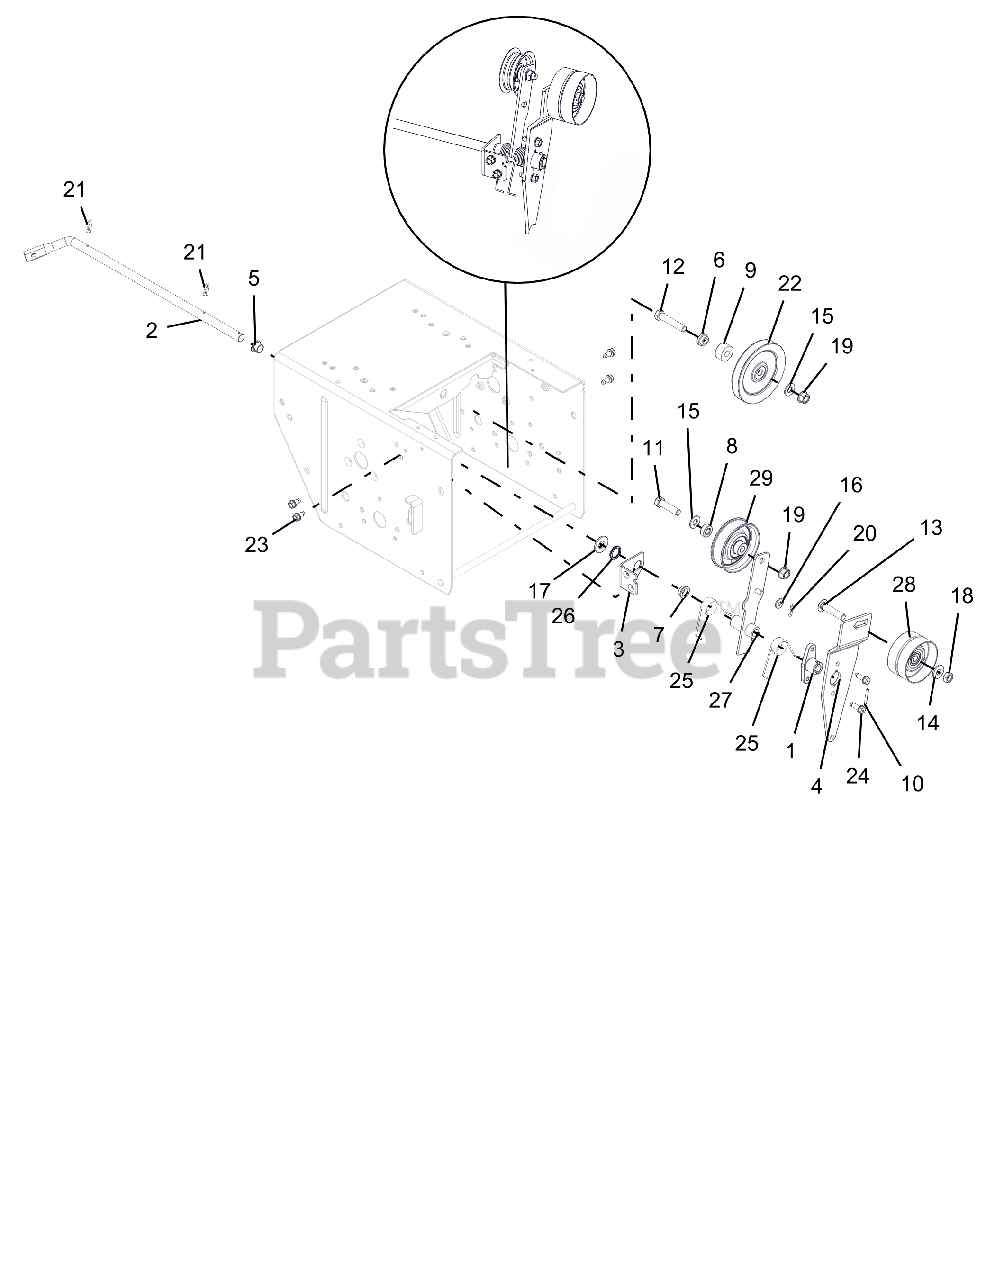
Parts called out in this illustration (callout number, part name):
1	HUB, BRAKE ARM
2	ARM, ATTACHMENT
3	BRACKET, SUPPORT
4	ARM, IDLER-ATTACHMENT
5	BUSHING, POLYLINER-.50 SPLIT
6	BSHG, FLANGE .391X.56X.313X.75
7	BSHG,FLANGE .500X.625X.270X.75
8	SPCR, BRG .315X.500X.358X.281
9	BSHG,POCKET .391X.570X1.0X.450
10	PIN-ROLL .125X1.00
11	@BLT-HEX .38-16X1.50 GR5 YWZC
12	@BLT-HEX .38-16X2.00 GR5 YWZC
13	@BLT-RHDSSQNK .38-16X1.75 G5YZ
14	@WSHR-FL-STL.38X.875X.083 YWZC
15	@WSHR-FL-STL.406X.812X.065 YWZ
16	@WSHR-FL-STL.281X.62X.065 YWZC
17	@WSHR-FL-STL.531X1.06X.095YWZC
18	@NUT-LK-CTR-JAM .375-16 YWZC
19	@NUT-LK-TOP-FLG .38-16 YWZC
20	PIN-HAIR INT .06X.18X.77
21	CLIP, SPRING
22	SHV, .38"ID X 4.00"OD V-IDLER
23	SCR-TAP .25-20X.50 HWH TR YWZ
24	SCR-TAP-PM .25-20X.75 TR YWZ
25	SG-TORS .067X.88
26	WAVE SPRING .600X.875X.25FH
27	ARM, TRACTION CLUTCH
28	IDLER, FLAT-2.75 OD X .375 ID
29	IDLER, FLAT - 3.05" X .75"
